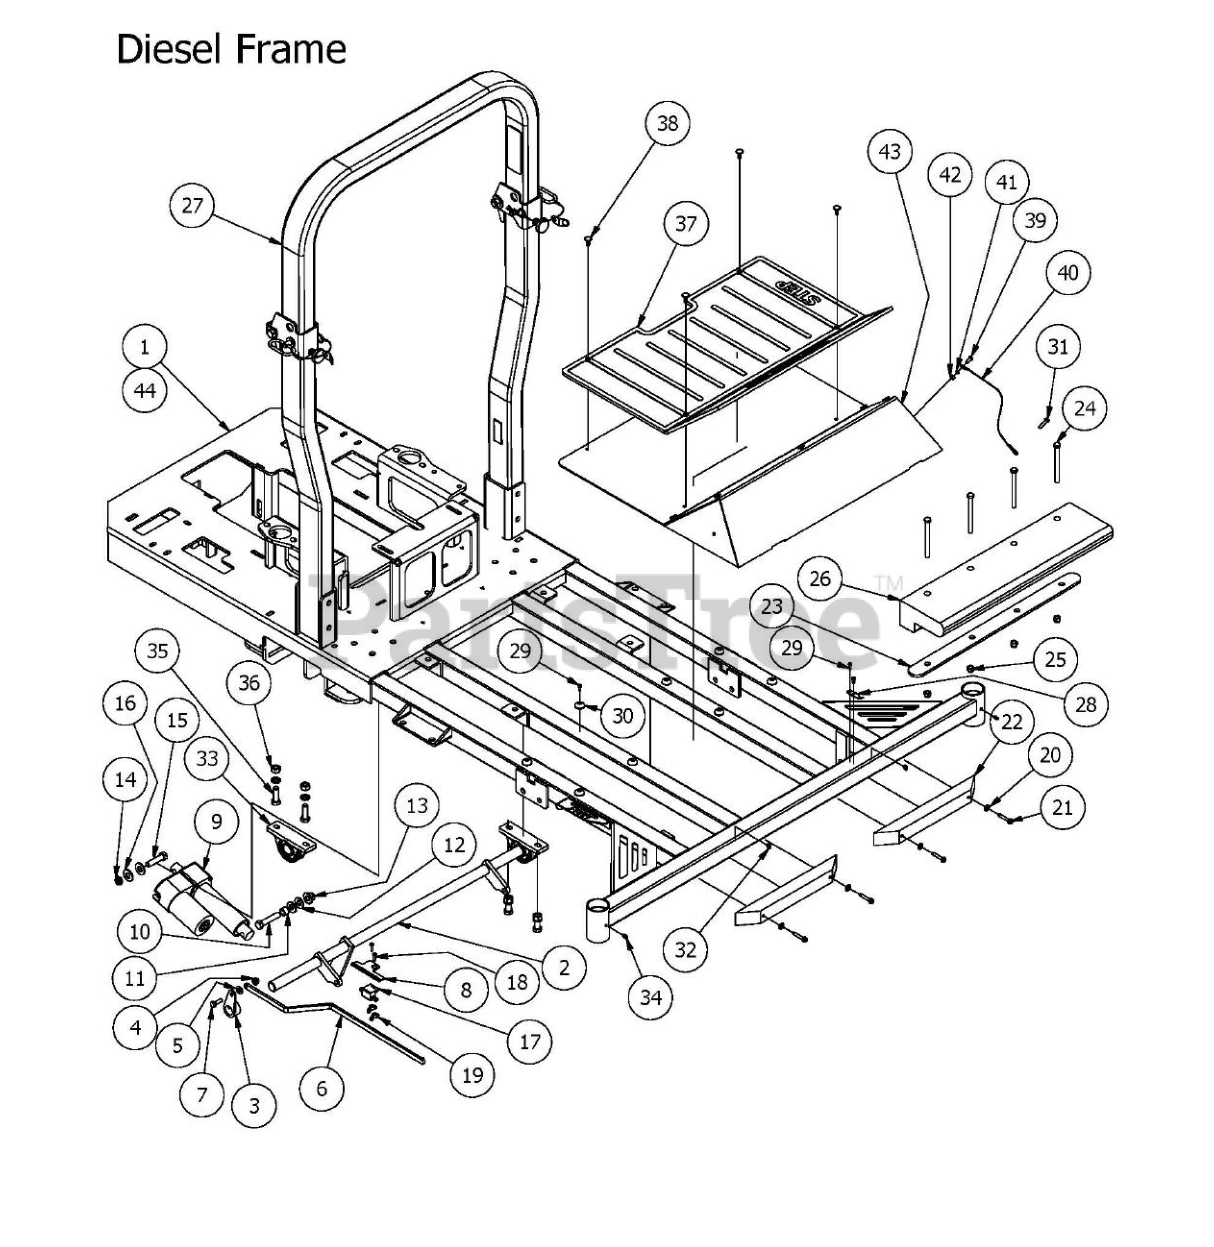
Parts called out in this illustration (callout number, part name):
1	Diesel 4cyl 72" Frame
2	Actuator Bar
3	Height Indicator Lever
4	5/16" Flange Nut
5	.360 ID Plastic Washer
6	Height Indicator Bar
7	5/16" x 1" Bolt
8	Deck Stop Bracket 2008
10	1/2" x 2 1/2" Hex Bolt
11	1/2 x 1/2 Spacer
12	.505 Nylon Spacer
13	1/2-13 Nylon Flange Nut-Orange
14	1/2" Nylock Nut (1/2 Jam)
15	1/2" x 2" Hex Bolt
16	1/2" Washer (Grade 8)
17	Deck Stop Switch
18	1024 x 1" Allenhead Bolt
19	10-24 Wing Nut
20	1/4" Flat Washer
21	1/4" x 1 1/2" Self Tapping Screw
22	14" Rubber Bumper
23	Diesel Weight Bar Bracket
24	3/8" x 4 1/2" Bolt
25	3/8 Nylock Nut
26	58lb Diesel Weight
27	2014 & Newer Diesel 2x3 Folding ROPS
28	2006 Floor Panel Stop
29	#10 x 1/2" Self Tapping Screw
30	Button Bumper
31	1/4 x 1 Hex Head tek screw
32	Brass Washer for Weld-On Hinge
33	pillow block 2bolt sealmaster
34	1/4" Press in Grease Fitting
35	1/2" x 1 1/2" Hex Bolt
36	1/2" Hex Nut
37	AOS Floor Mat
38	5/8" Christmas Tree Fastener
39	1/4" x 5/8" Buttonhead Bolt
40	Floor board Cable W/ Swivel Ends
41	1/4" Lock Washer
42	1/4" Hex Nut
43	Floor Panel
44	Diesel 4cyl 61" Frame Suspension
